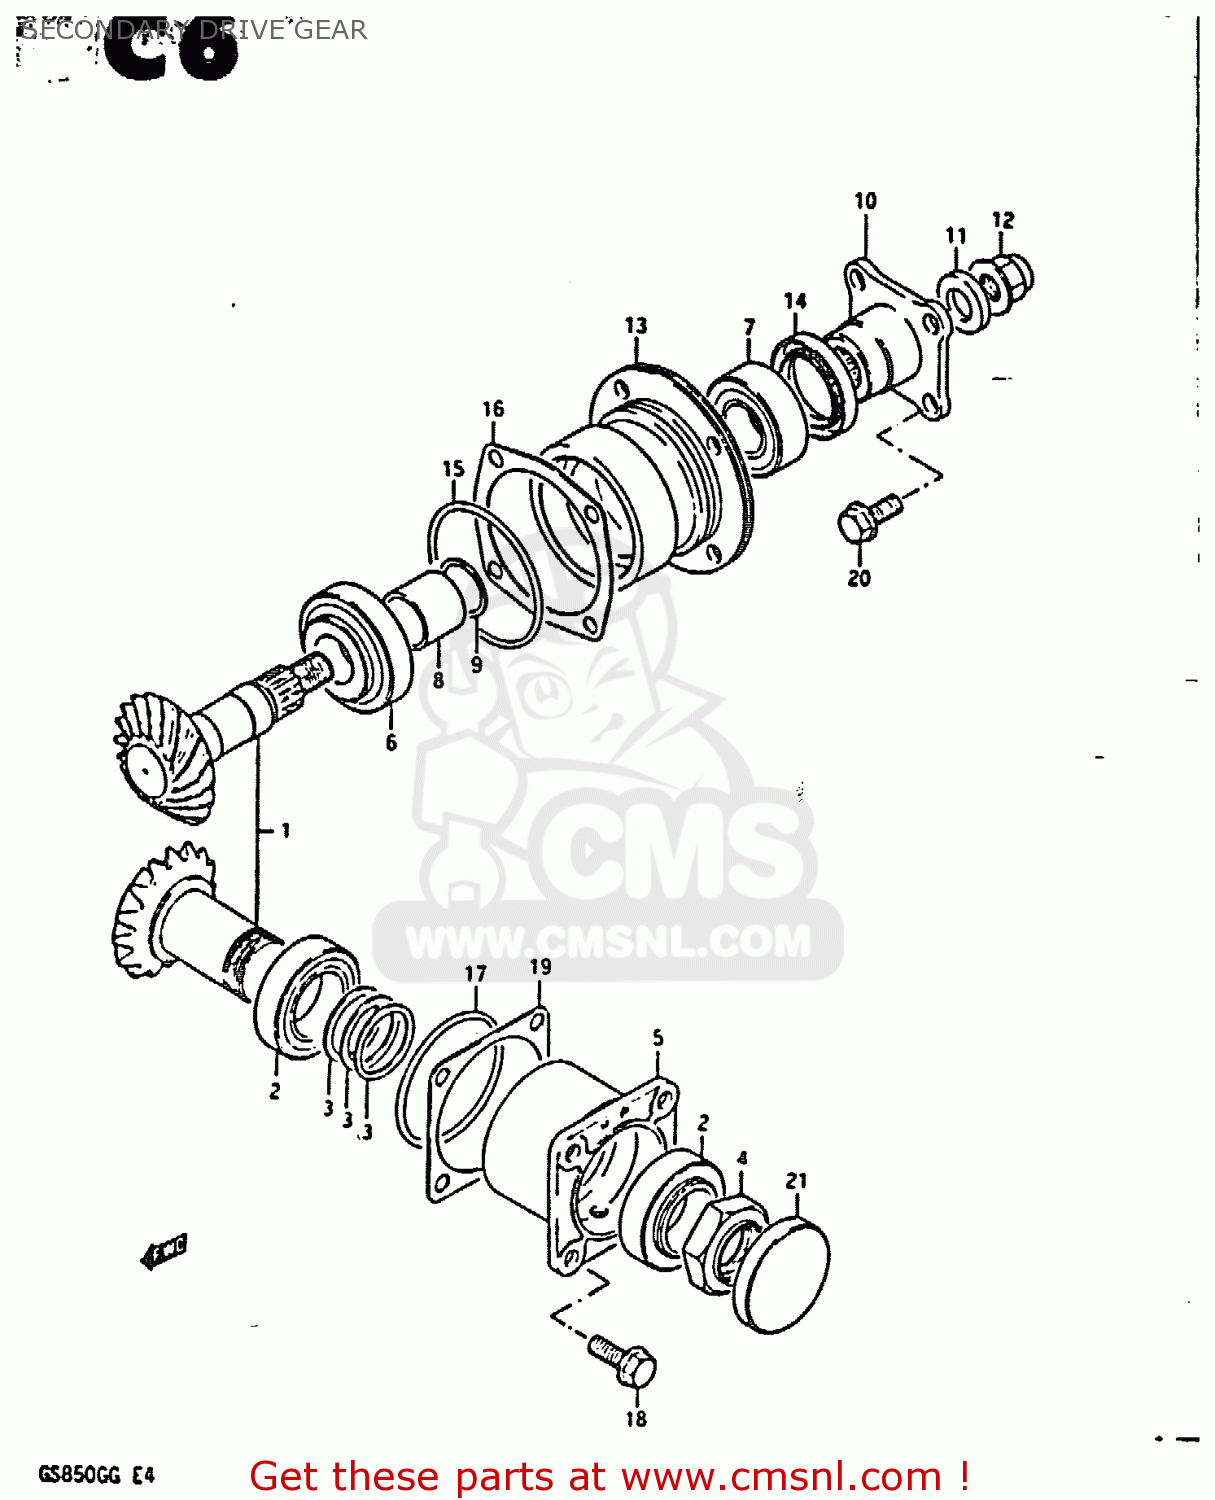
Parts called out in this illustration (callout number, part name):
1	GEAR SET,SECON
2	BEARING(32X58X17)
3	SHIM(32X38X2)
4	NUT
5	HOUSING,SECONDARY DRIVE
6	TAPER,ROLLER BEARING
7	BEARING
8	SPACER (25.2X30X40)
9	SHIM (25X30X2
10	FLANGE,UNIVERSAL JOINT
11	WASHER(14X29X4)
12	NUT
13	HOUSING,SECONDARY DRIVE
14	SEAL,OIL(35X52X9)
15	O RING(D:3.1,ID:69.4)
16	SHIM,DRIVEN GEAR HOUSING
17	O RING(D:2.4,ID:62.6)
18	BOLT
19	SHIM,SECONDARY DRIVE
20	BOLT
21	PLUG
